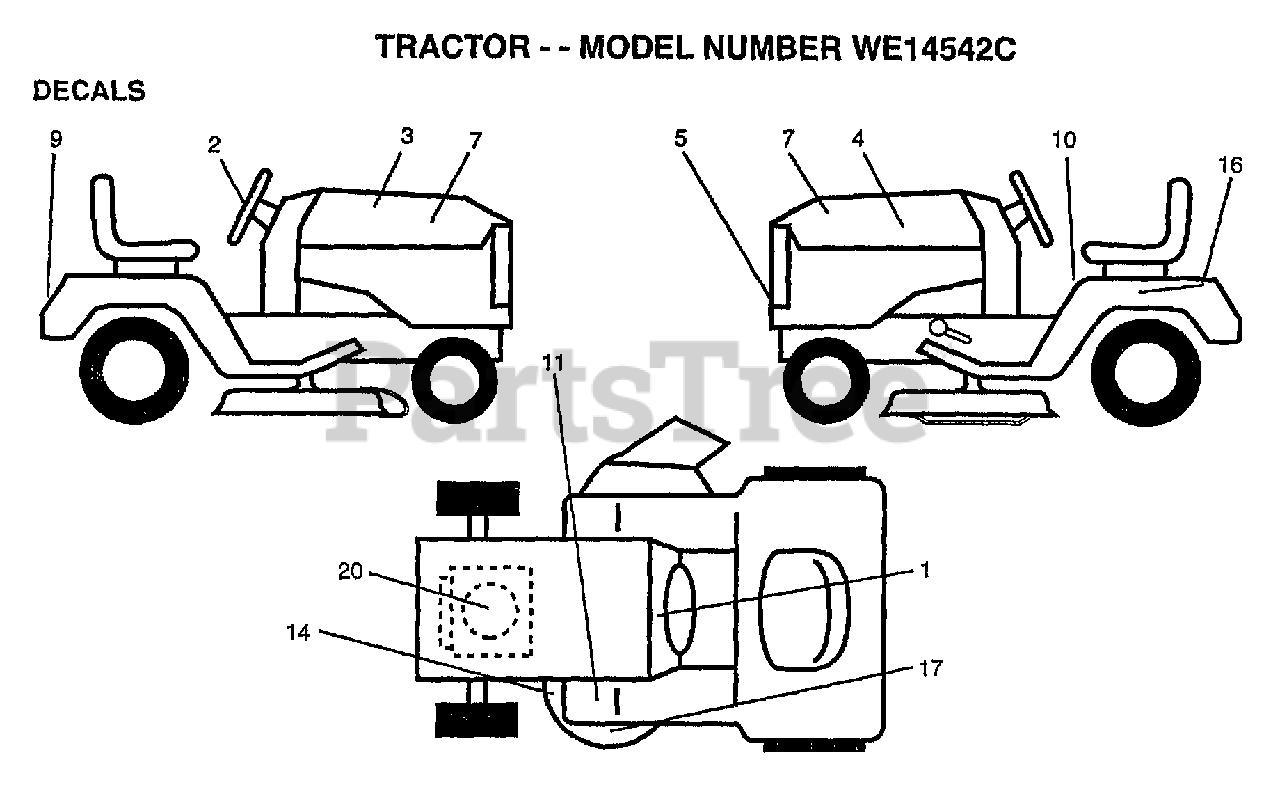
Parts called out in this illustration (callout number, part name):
1	"DECAL DASH,OPER."
2	"DECAL INS,STRG WH"
3	"DECAL HOOD,RH"
4	DECAL HOOD LH
5	"DECAL GRILLE,LENS"
7	"DECAL PANEL,SIDE"
9	DECAL-FENDER
10	"DECAL DANGER,FEND"
14	DECAL
16	DECAL.BATRY.3-3908
20	DECAL, ENGINE
